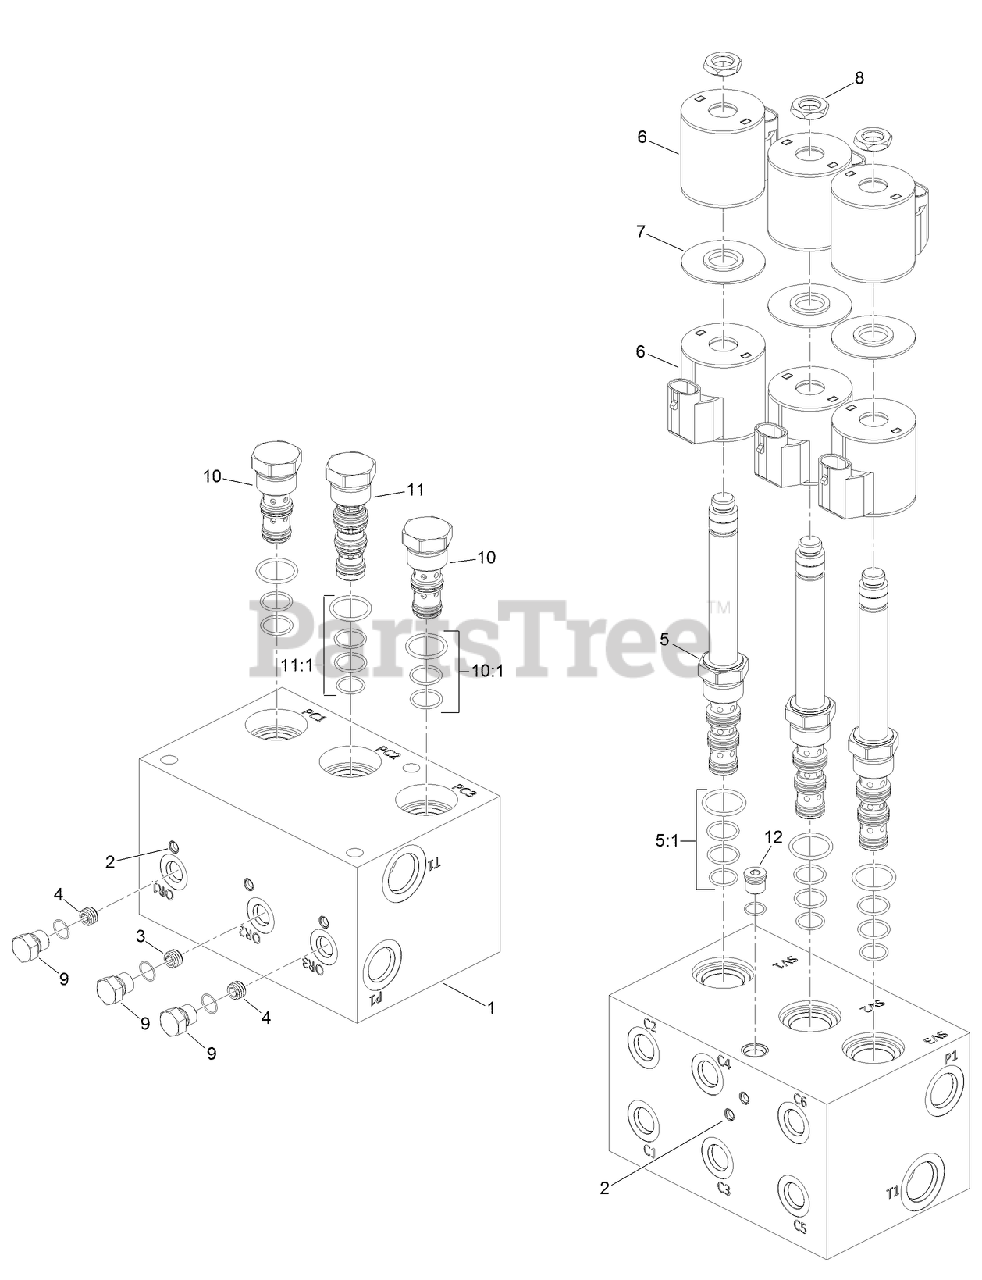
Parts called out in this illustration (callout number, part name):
1	BLOCK-MANIFOLD
2	Deck ASM
3	ORIFICE
4	ORIFICE
5	VALVE-CARTRIDGE, MOTOR SPOOL
5:1	SPOOL VALVE SEAL KIT
6	COIL-12V, DC
7	SPACER-E COIL
8	NUT-COIL
10	VALVE-CHECK
10:1	SEAL KIT
11	VALVE-CHECK
11:1	SEAL KIT
